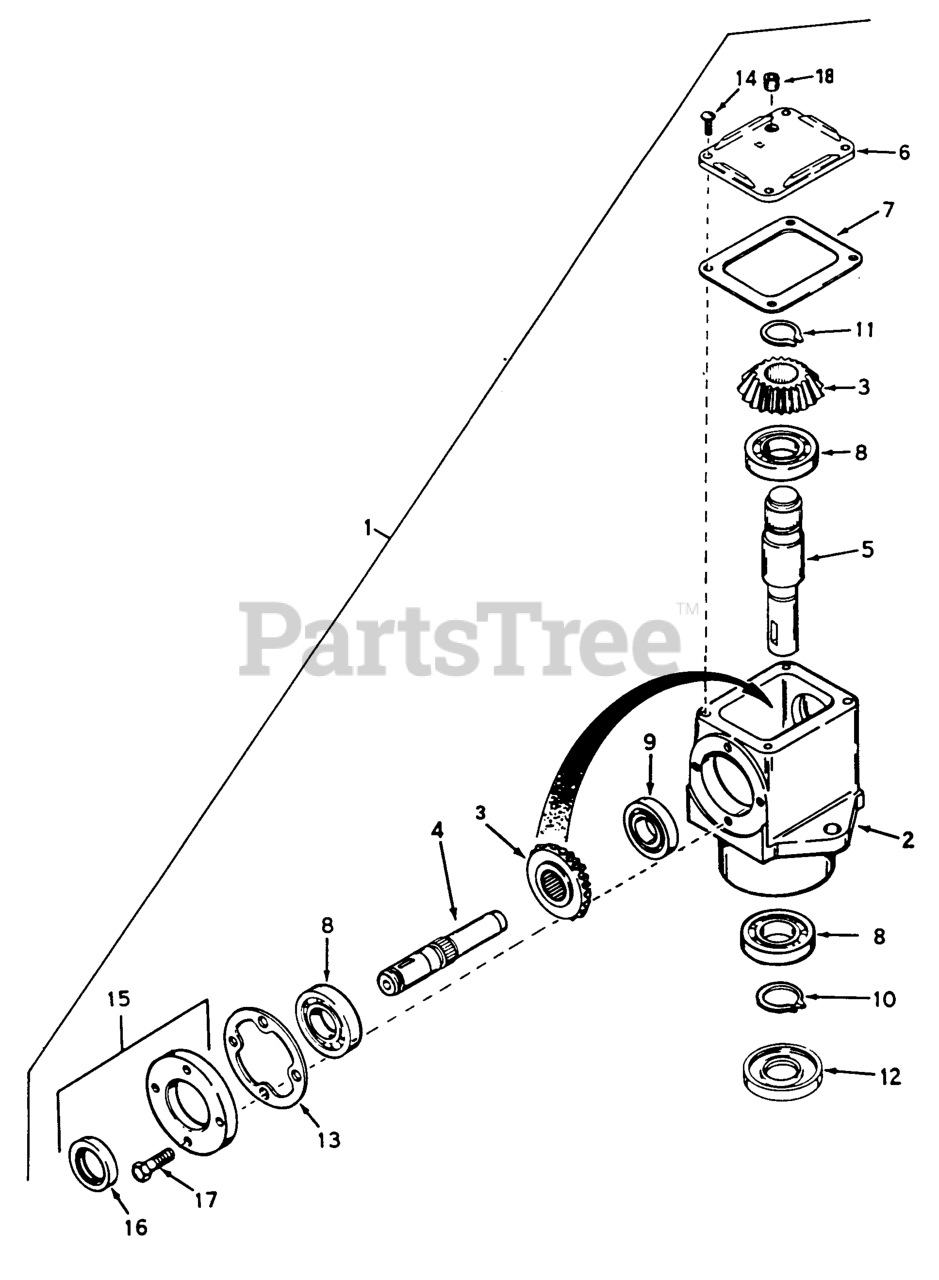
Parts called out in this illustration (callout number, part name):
1	Head Assy., Right Hand
2	Housing, Right Angle Drive
3	Gear, Miter
4	Shaft, Input Pinion
5	Shaft, Output
7	Gasket, Cover
8	Bearing, Ball
9	Bearing, Ball
10	Ring, Retainer
11	Ring, Retainer
12	Seal, Oil
13	Gasket, Cap
14	Screw Pan Hd. Self-Tap, 10-24 X 1/2
15	Cap & Seal Assy., Retainer
16	Seal, Oil
17	Screw, Hex Hd., 1/4-20 X 7/8
18	Plug, Pipe Hex Countersunk Headless, 1/8-27
